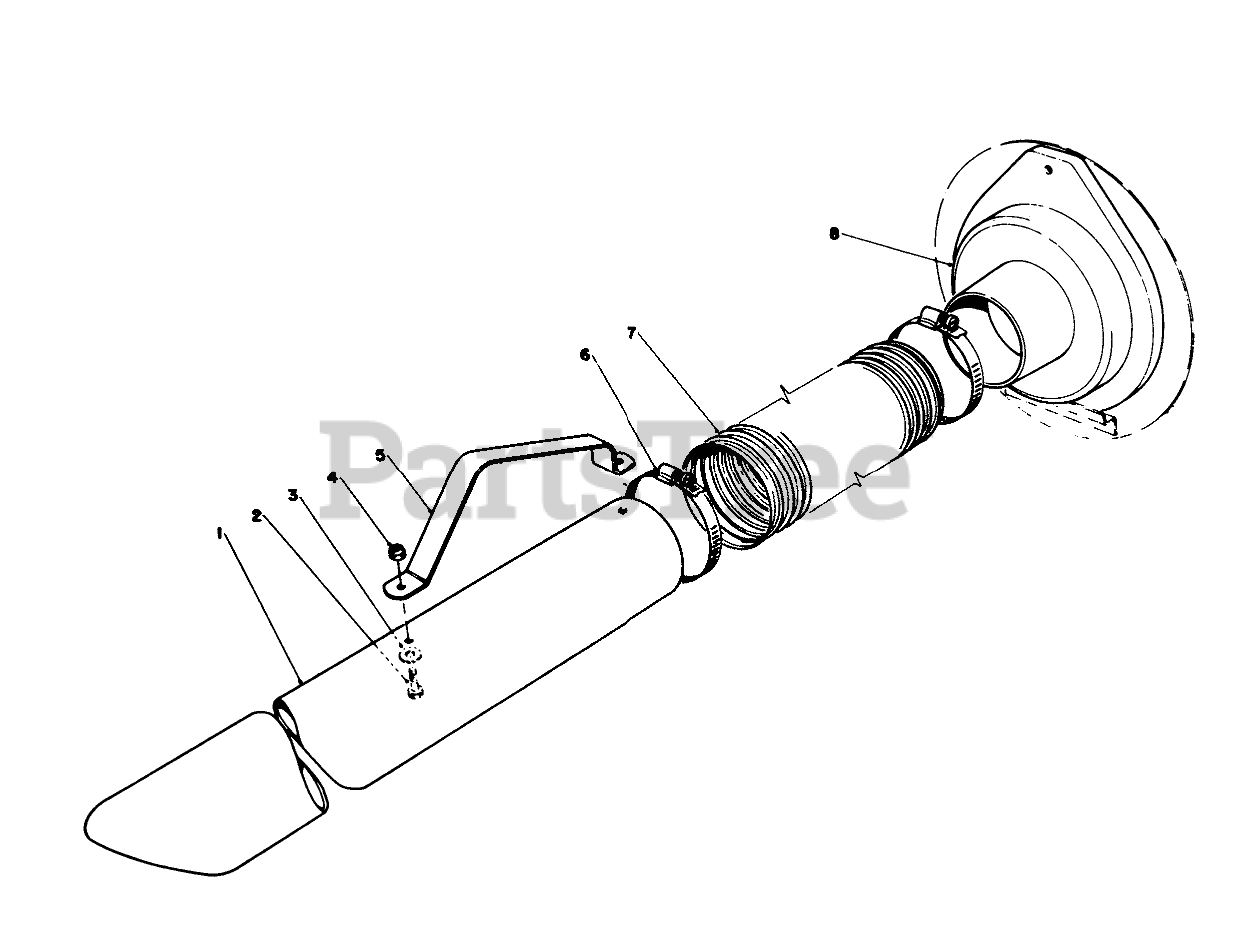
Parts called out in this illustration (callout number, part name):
1	NOZZLE HANDLE
2	Clamp
3	VACUUM HOSE
4	ADAPTOR HOSE TO HSG
5	NOZZLE HANDLE
6	CLAMP
7	VACUUM HOSE
8	ADAPTOR HOSE TO HSG
